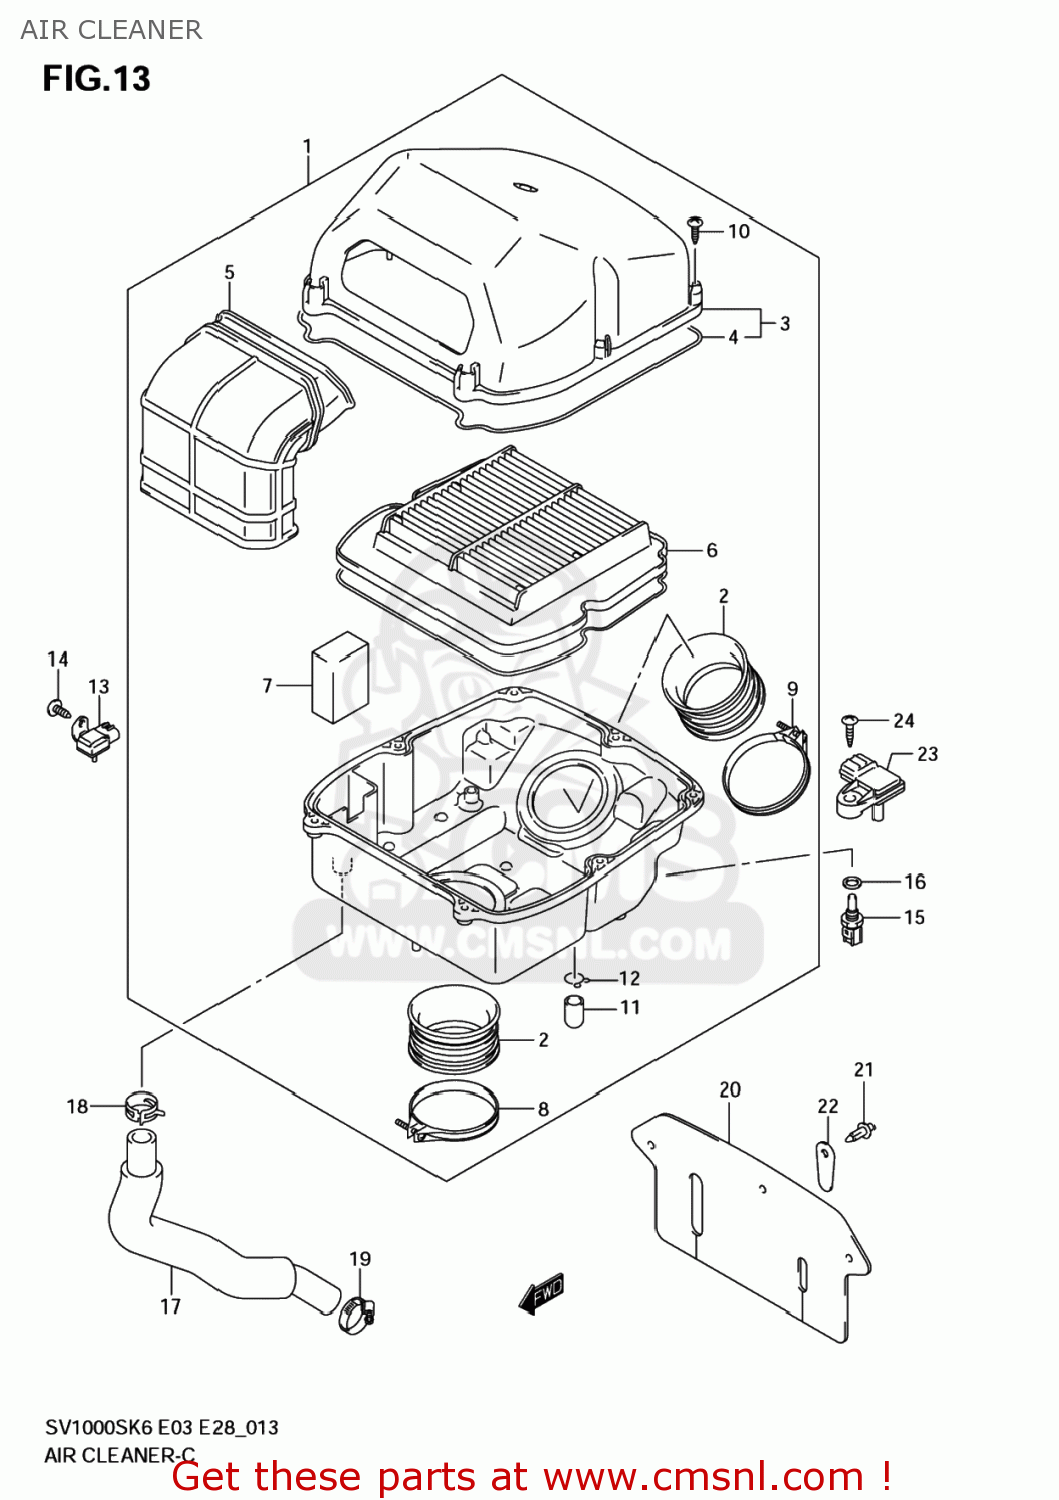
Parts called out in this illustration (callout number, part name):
1	CLEANER ASSY,AIR
2	TUBE,OUTLET
3	CAP,AIR CLEANER
4	GASKET (NAS)
5	TUBE,INLET
6	FILTER
7	FILTER,BREATHER
8	CLAMP
9	CLAMP
10	SCREW
11	PLUG
12	CLIP
13	SENSOR,BOOST
14	SCREW
15	SENSOR,WATER TEMP
16	GASKET(12X17X1) (NAS)
17	TUBE,BREATHER
18	CLIP
19	CLAMP
20	GUARD,WATER
21	CLIP
22	PLATE,WATER GUARD
23	SENSOR,BOOST
24	SCREW
